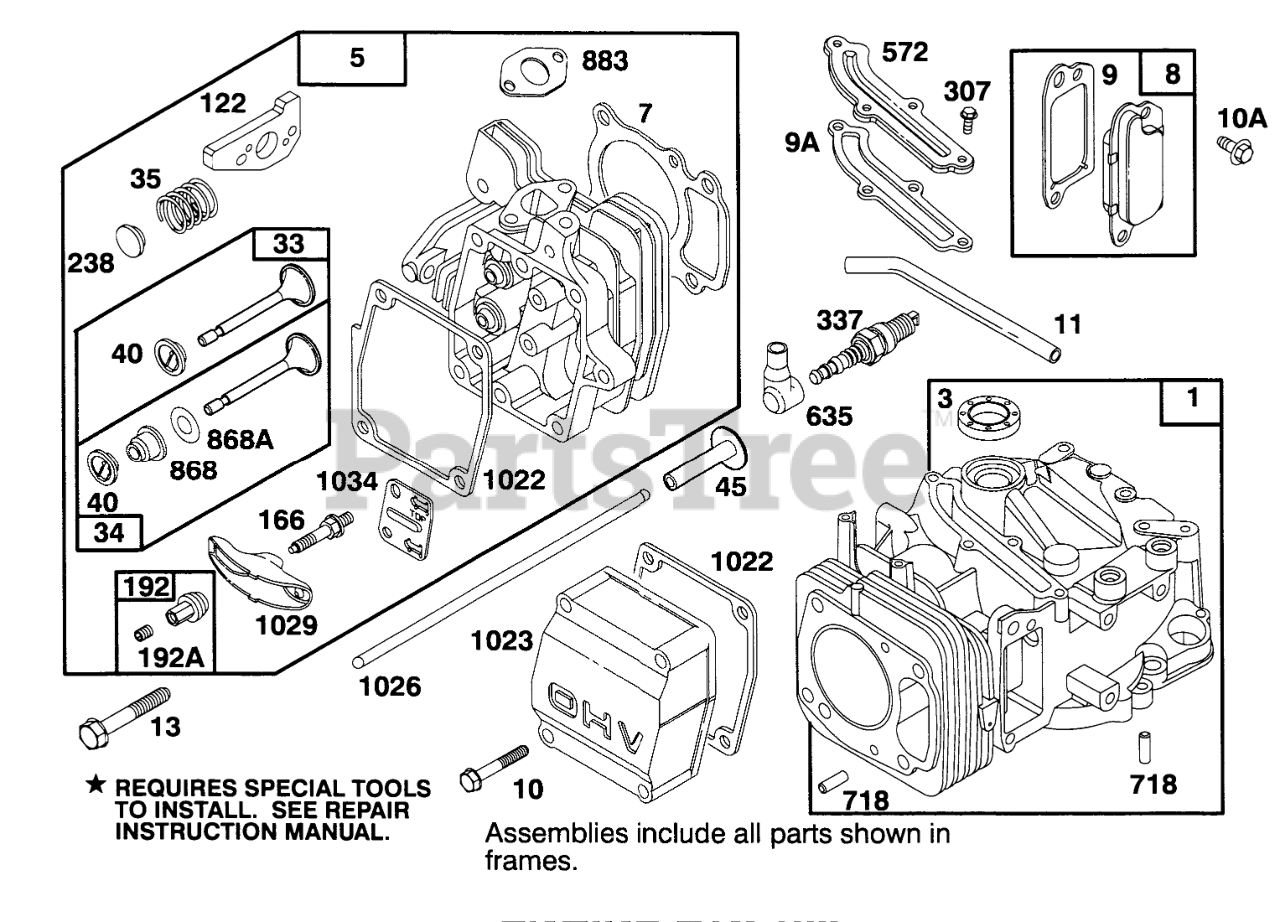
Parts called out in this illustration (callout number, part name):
1	CYLINDER ASSEMBLY
3	SEAL - OIL
5	CYLINDER HEAD
7	CYLINDER HEAD GASKET
8	Breather Assy
9	BREATHER GASKET
9A	GASKET-BREATHER
10	HEX HEAD SCREW
10A	HEX HEAD SCREW
11	TUBE - BREATHER
13	CYLINDER HEAD SCREW
33	EXHAUST VALVE
34	INTAKE VALVE
35	VALVE SPRING
40	SPRING RETAINER
45	VALVE TAPPET
122	ADAPTER ASSEMBLY
166	ROCKER ARM STUD
192	NUT - HEX SPECIAL
192A	SCREW SET
238	VALVE CAP
307	SCREW - SEM
337	PLUG-SPARK
572	BAFFLE - CYCLINDER
635	SPARK PLUG ELBOW
718	DOWEL - SLEEVE
868	SealAssy-Valve
868A	Seal-Valve
883	EXHAUST GASKET
1022	ROCKER COVER GASKET
1023	COVER - VALVE
1026	PUSH ROD
1029	ROCKER ARM
1034	PUSH ROD GUIDE
